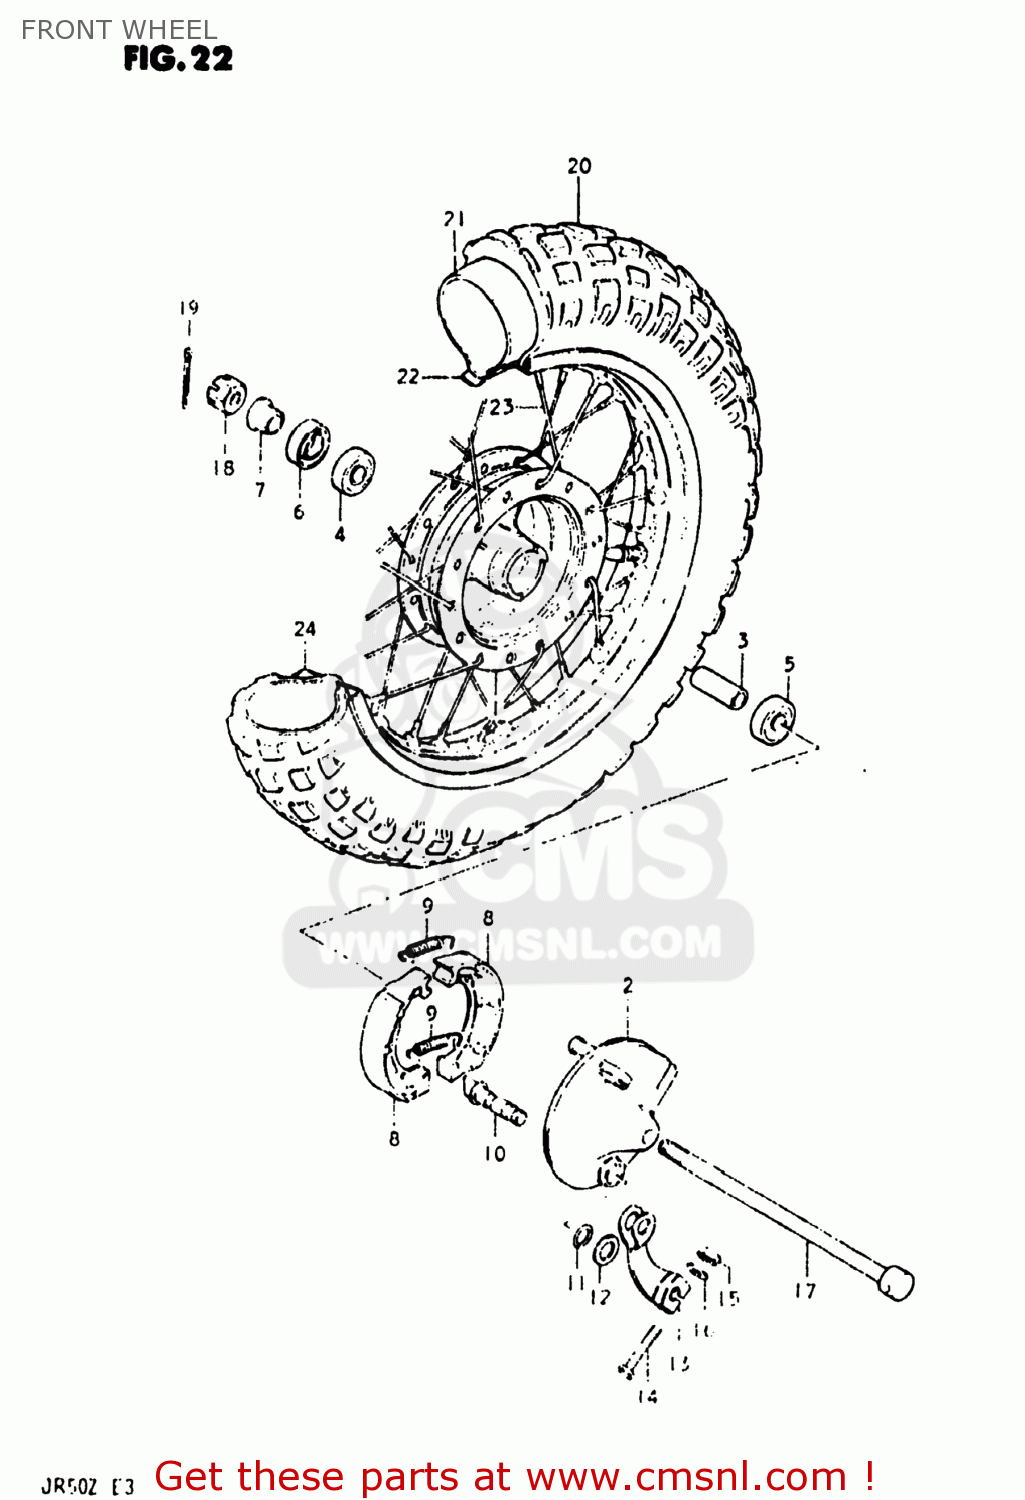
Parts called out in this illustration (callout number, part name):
1	HUB,FR WHEEL
2	PANEL,FR BRAKE ANCHOR
3	SPACER(10.2X16X47)
4	BALL BEARING K
5	BEARING
6	SEAL,OIL(15X27X6)
7	SPACER,AXLE
8	SHOE,BRAKE
9	SPRING(L:34)
10	CAM,FRONT BRAKE
11	O RING(D:2.4,ID:9.8)
12	WASHER (10.5X18X1)
13	LEVER,FR BRAKE CAM
14	BOLT
15	NUT
16	WASHER
17	AXLE,RR
18	NUT
19	PIN 20X20
20	TIRE
21	TUBE,INNER
22	PROTECTOR,INNER TUBE
23	SPOKE SET,RR
24	RIM,WHEEL
